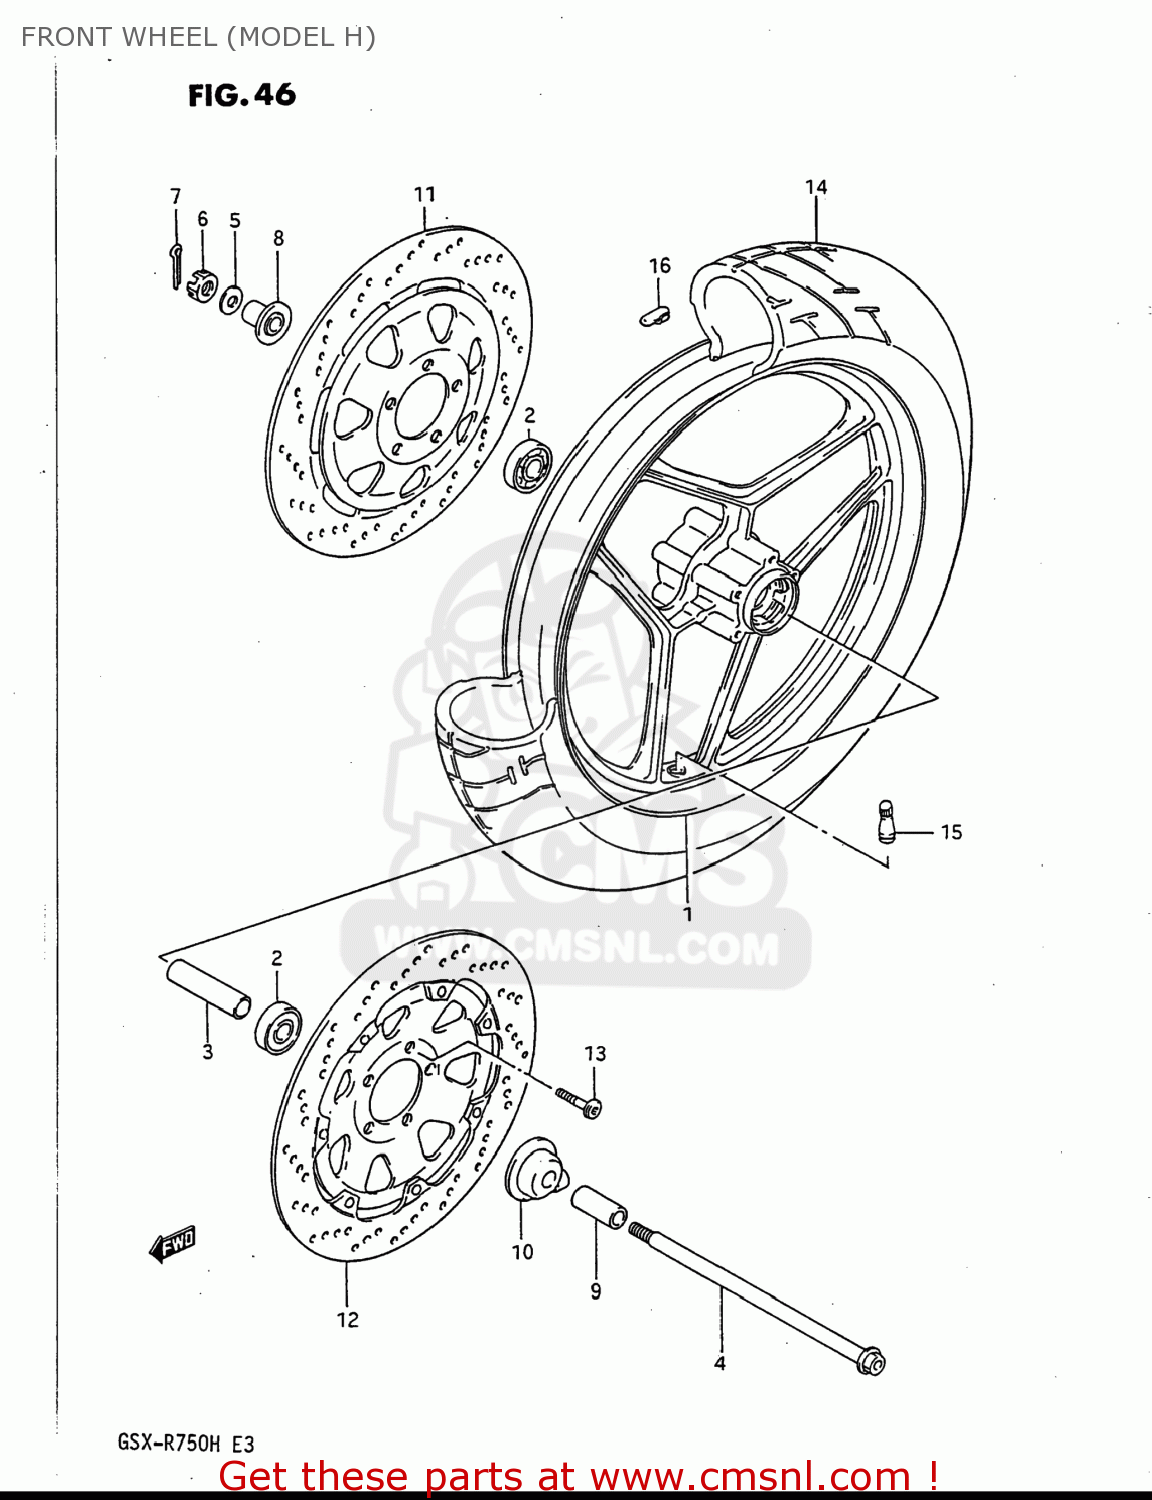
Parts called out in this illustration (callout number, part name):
1	WHEEL,FRONT (2.50X18)
2	BEARING(17X42X13)
3	SPACER (17.3X24X78)
4	AXLE,FRONT
5	WASHER
6	NUT
7	PIN,COTTER
8	SPACER,FR HUB,R
9	SPACER,FR AXLE
10	BOX ASSEMBLY,SPEEDOMETER GEAR
11	DISC,BRAKE
12	DISC,BRAKE
13	BOLT
14	TIRE,FRONT
15	VALVE,TIRE
16	BALANCER,WHEEL
